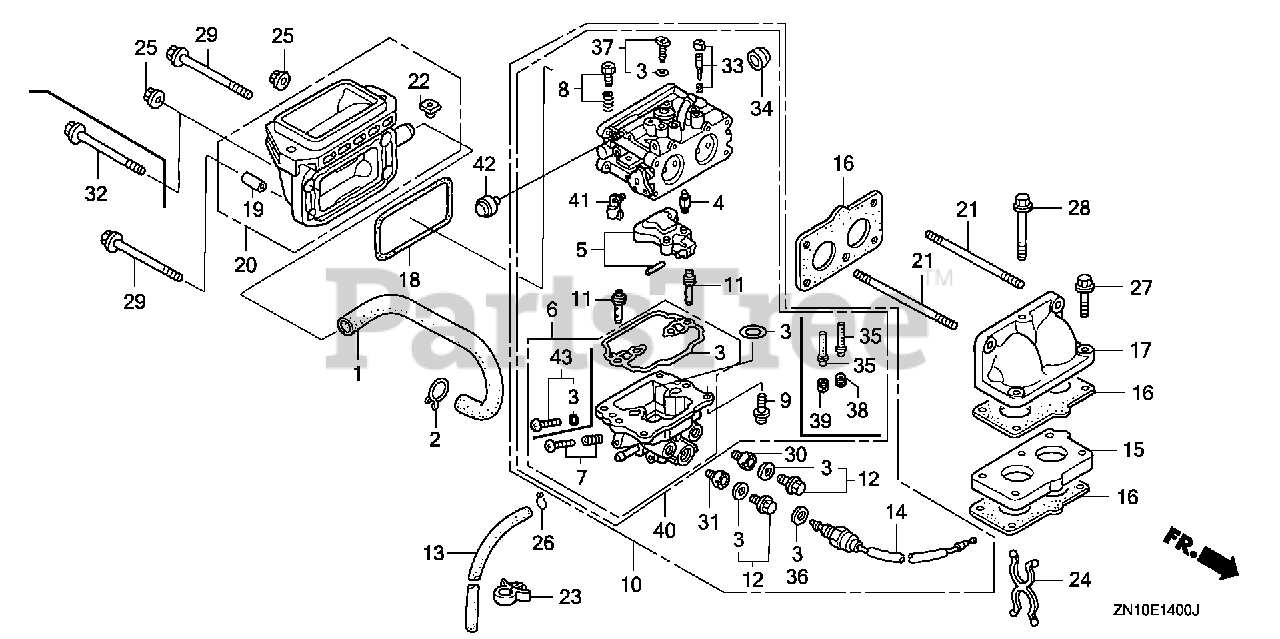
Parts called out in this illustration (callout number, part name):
1	TUBE, BREATHER
2	CLIP, BREATHER TUBE
3	GASKET SET (CARBURETOR NO.)
4	VALVE SET, FLOAT (CARBURETOR NO.)
5	FLOAT SET (CARBURETOR NO.)
8	SCREW SET, THROTTLE (CARBURETOR NO.)
9	SCREW, PAN (4X12)
10	CARBURETOR ASSY. (BK01D B)
13	TUBE, DRAIN
14	VALVE ASSY., SOLENOID (KEIHIN) (CARBURETOR NO.)
15	INSULATOR, CARBURETOR
16	GASKET, CARBURETOR
17	ELBOW, MANIFOLD
18	GASKET, AIR CLEANER
19	COLLAR A, AIR CLEANER
20	ELBOW, AIR CLEANER
22	NUT, INSERT (6MM)
23	CLIP B, CABLE (9MM BLACK)
24	CLIP, PURSE LOCK
26	CLIP, TUBE (B8)
27	BOLT, FLANGE (6X30)
28	BOLT, FLANGE (6X65)
29	BOLT, FLANGE (6X90)
32	BOLT, FLANGE (6X90)
33	SCREW SET, PILOT (CARBURETOR NO.)
34	CAP, CHOKE DUST (CARBURETOR NO.)
35	NOZZLE, MAIN (CARBURETOR NO.)
36	WASHER, PLAIN (CARBURETOR NO.)
37	JET SET, PILOT (#38)
38	JET, MAIN (#85)
38	JET, MAIN (#90) (CARBURETOR NO.)
38	JET, MAIN (#95) (CARBURETOR NO.)
39	JET, MAIN (#88)
39	JET, MAIN (#92)
39	JET, MAIN (#98)
41	ARM, THROTTLE LINKAGE
43	SCREW SET, DRAIN (CARBURETOR NO.)
